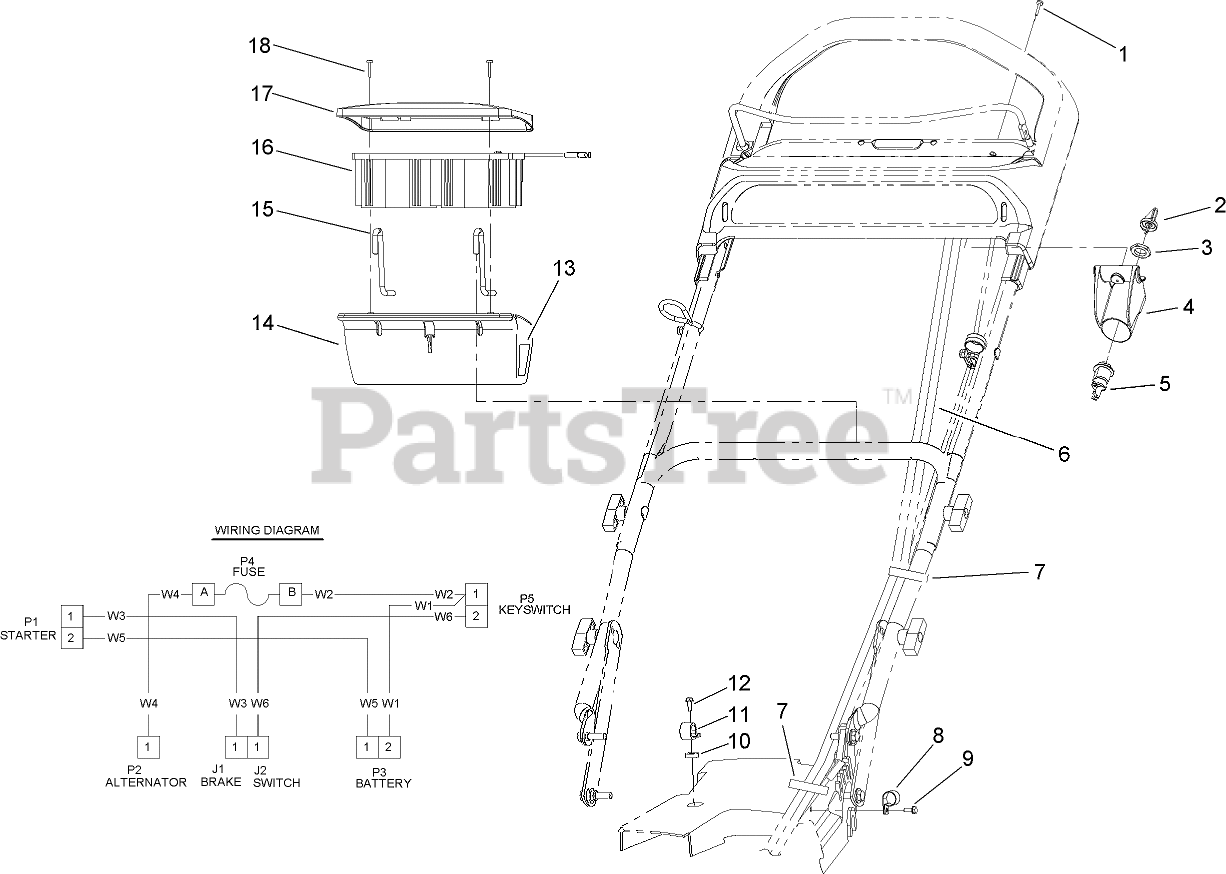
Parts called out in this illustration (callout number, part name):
1	SCREW-PPH, PLASTITE
2	KEY-IGNITION
3	NUT-HH
4	SWITCH-HOLDER
5	STARTER SWITCH ASM
6	WIRE HARNESS - CAST QUANT PP
7	TIE-CABLE
8	CLAMP-CABLE
9	SCREW-HWH
10	WASHER
11	CLAMP-CABLE
12	SCREW-SPECIAL
13	DECAL - INSTRUCTION
14	BOX-BATTERY
15	ROD-BATTERY
16	BATTERY
17	COVER-BATTERY
18	SCREW-PPH
